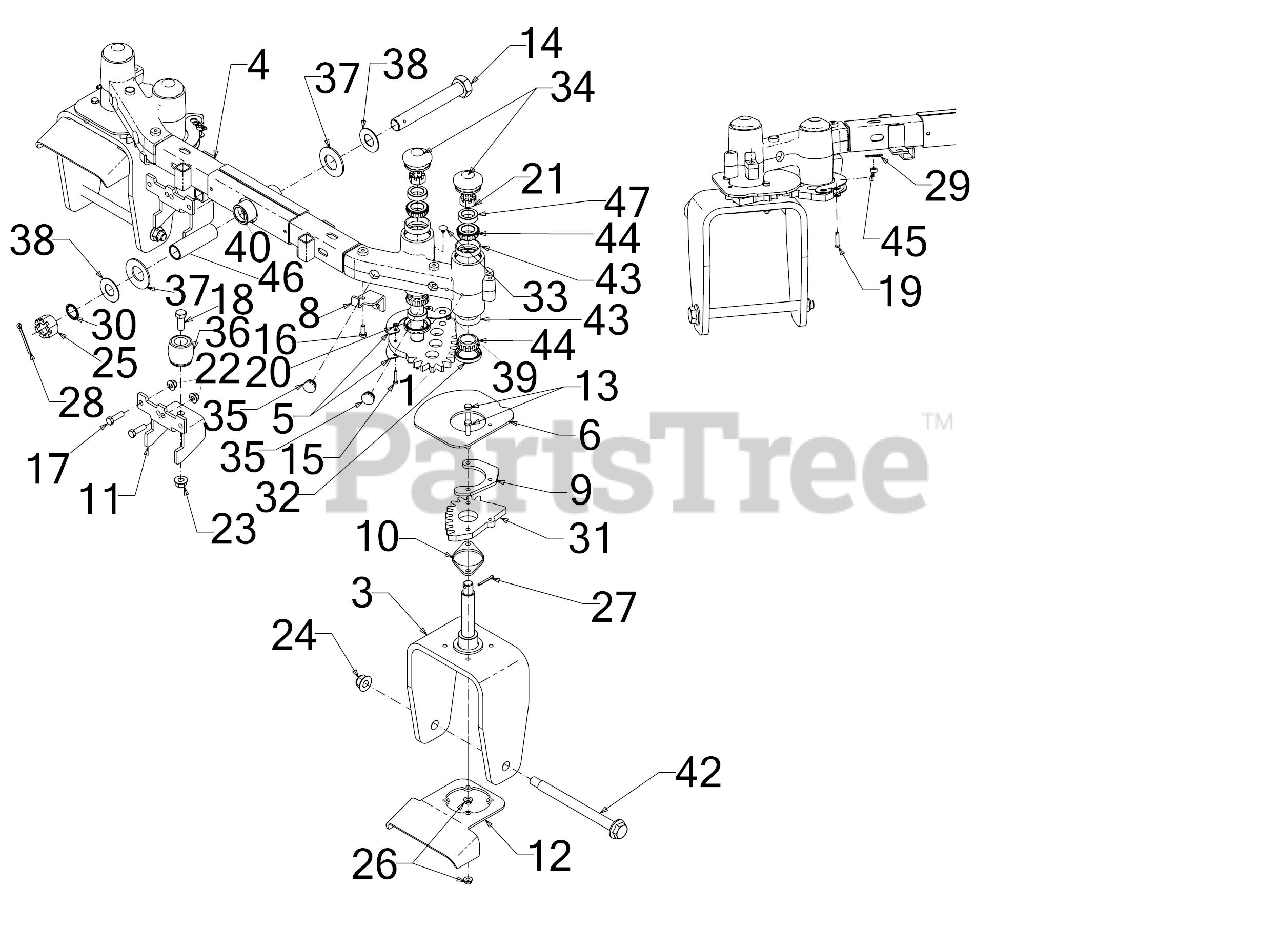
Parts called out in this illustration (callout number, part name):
1	STEERING GEAR (LH)
3	FRONT YOKE ASSEMBLY (STEERING)
5	CABLE GEAR MOUNTING BRACKET
8	CABLE MOUNTING BRACKET (LH)
9	GEAR SPACER PLATE
10	LOWER GEAR SPACER PLATE
11	BUMPER MOUNTING BRACKET
13	HEX SCREW 5/16-18 x 2.25 GR5
14	HEX HEAD SCREW 1-14 X 7 GR5
15	SCREW #10-24 x 1.00 GR5.1
16	SCREW 5/16-18 x .750
17	SCREW 3/8-16 x 1.25 GR5
18	SCREW 1/2-13 x 1.25 GR5
19	CLEVIS PIN .25 x 1.00
21	HEX NUT CASTLE 3/4-16
24	FLANGE LOCK NUT
25	CASTLE NUT 1.0-14 GR5
26	HEX FLANGE NUT
27	COTTER PIN-5/32 DIA
28	COTTER PIN
29	BOW TIE COTTER PIN 1/4-5/16
30	RETAINING RING
31	STEERING GEAR YOKE
33	RATCHET CLIP
34	AXLE GREASE CAP
36	AXIAL BUMPER
37	BELL WASHER 1.25ID x 2.5 x .180
38	FLAT WASHER 1.0 x 2.0 x .075
39	GREASE ZERT 1/4-28
40	GREASE FITTING
42	SHOULDER BOLT .750 X 8.175:5/8-11
43	BEARING CUP
44	BEARING CONE
